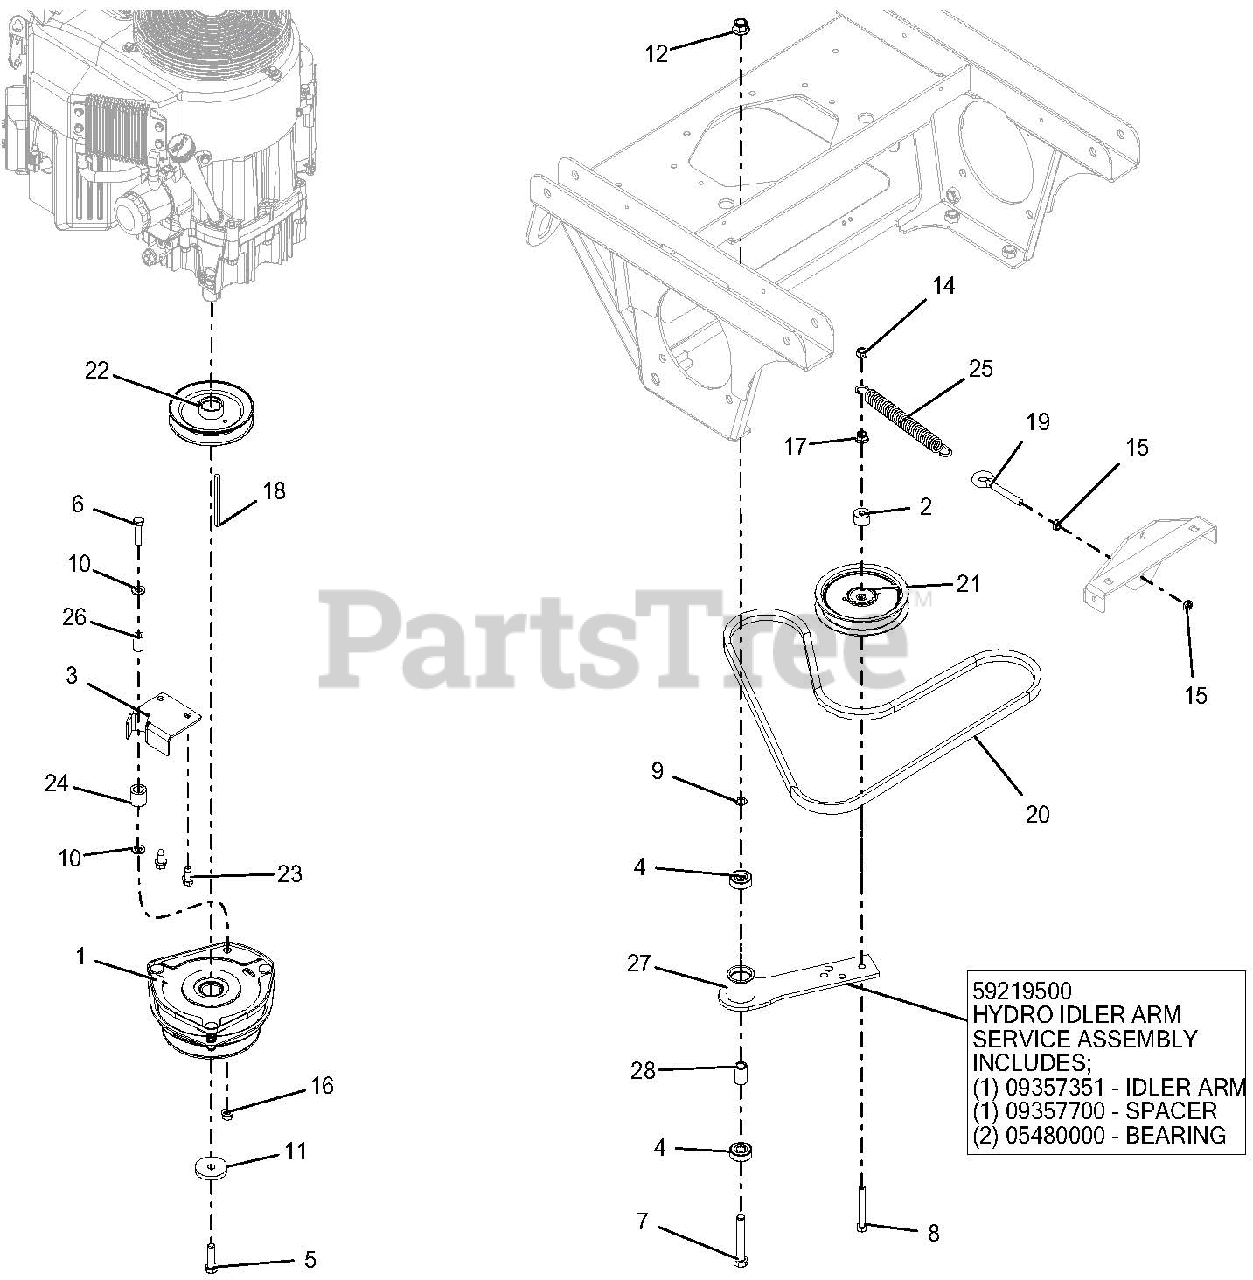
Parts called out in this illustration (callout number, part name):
1	CLUTCH-OGURA
2	SPACER .390X1.000X.562
3	WLDMT, CLUTCH STOP
4	BRG-BALL .500X1.375X.44
5	BLT-HEX .44-20X1.50 GR8 YWZC
6	BLT-HEX .38-16X1.50 GR5 YWZC
7	BLT-HEX .50-13X3.00 GR5 YWZC
8	BLT-HEX .38-16X2.75 GR5 YWZC
9	WASHER-FLAT-STL, .500 X .750 X .020
10	WSHR-FL-STL.406X.812X.065 YWZ
11	WSHR-FL-STL .469X2.00X.25 YWZC
12	NUT-LK-NYL-FLG .50-13 YWZC
14	NUT-LK-CTR .38-16 YWZC
15	NUT, JAM .375-16 YWZC
16	NUT, LK-TOP-FLG .38-16 YWZC
17	NUT-LK-NYL-FLG .38-16 YWZC
18	KEY-SQ .250X.250X3.50
19	BOLT, EYE .375-16
20	BELT, B RAW COGGED
21	IDLER, FLAT - 5.00"
22	SHEAVE, ENGINE 1.127 ID X 5.250 OD-BLACK
23	SCR-TAP .38-16X.75 HWH TR YWZ
24	BUMPER, RUBBER .62 X 1.0 X .88 LG
25	SPRG, EXTENSION .120X.845X6.55 WLD
26	BUSH.,S.391X.622X.95 ST REV A
27	WLDMT, HYDRO DRIVE IDLER ARM-BLACK
27	HYDRO IDLER ARM SERVICE ASSEMBLY
27	IDLER ARM
27	SPACER
27	BEARING
28	SPACER, .510 X .750 X 1.148
